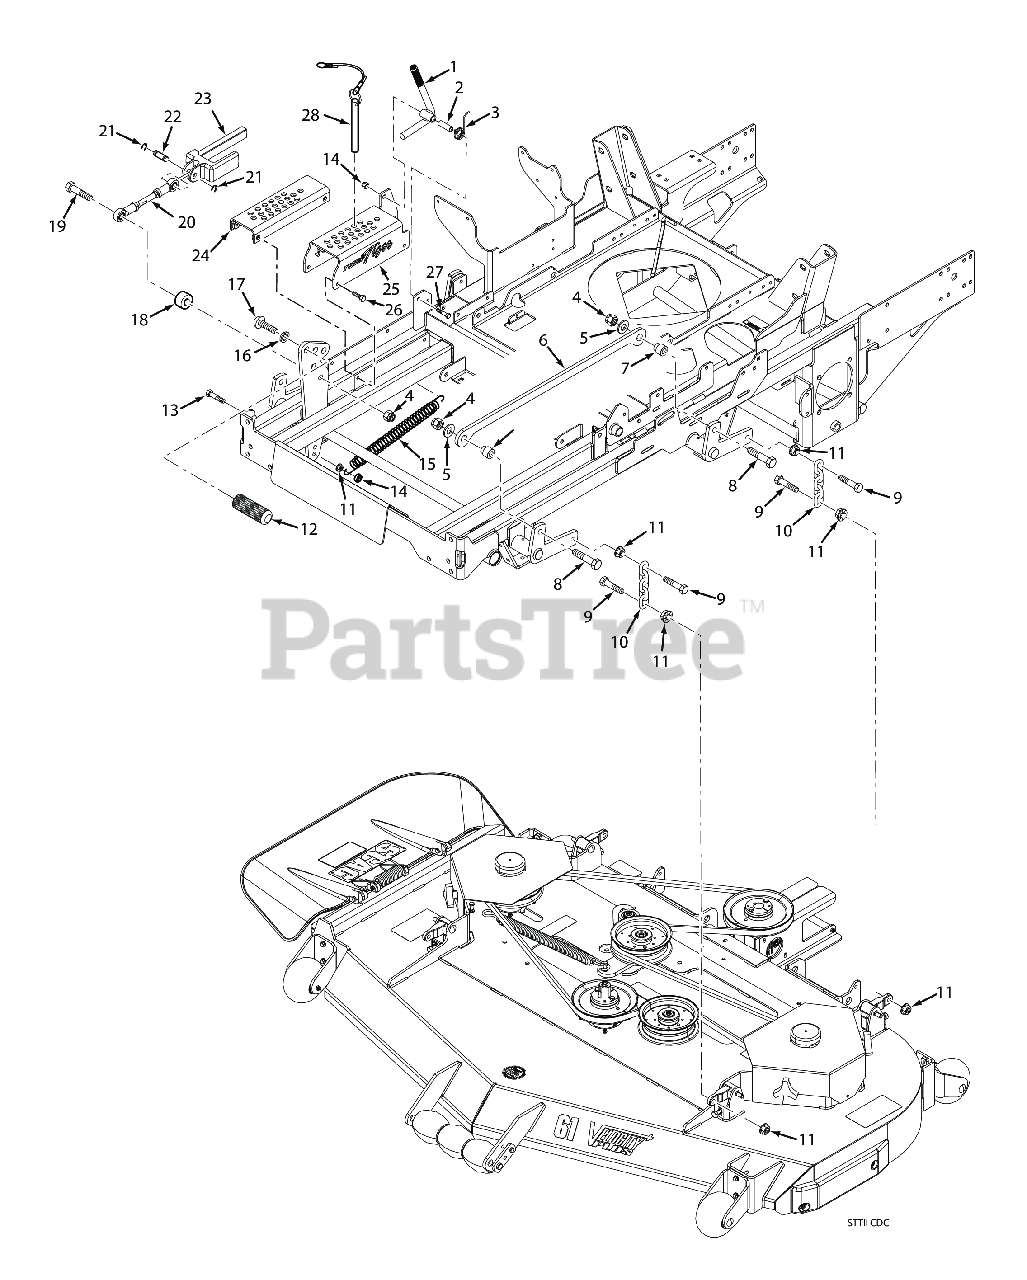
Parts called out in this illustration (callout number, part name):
1	Deck Latch Weldment w/Grip
1	Mounting Bracket, Fuel Tank
2	Bushing, .502 O.D.
3	Spring, Torsion - Lever Return
4	HEX LOCKNUT, ELASTIC STOP, 1/2-13
5	Flat Washer, 1/2 (.562 x 1.375 x .109)
6	Link, Deck Lift
7	Pivot, Deck Link
8	Bolt, Hex Head 1/2-13 x 2-1/4"
9	Bolt, Hex Head, 3/8-16 x 1-1/2"
10	Footplate
11	NUT, 3/8-16 SERRATED FLANGE HEX HEAD
12	Foot Pedal, Height Adjustment
13	Bolt, Hex Head 3/8-16 x 1-1/2" Grade 8 Black
14	Bolt, Hex Head 3/8-16 x 1" Ser. Flg.
15	Spring, Helper (61" & 72" Cutter Decks Only)
16	Lockwasher, 5/8" Spring
17	Bolt, Head Socket 5/8-11 x 1-1/2"
18	Spacer, Radiator
19	Hex Head Bolt, 1/2-13 x 2"
20	Linkage Assembly, Deck Lift
21	Retaining Ring, 1/2" Ext. "E"
22	Pin, Deck Lift
23	Slide, Height Adjustment
24	Weldment, Lower Cutting Height
25	Adjustment Bracket, Cutting Height Upper
26	Bolt, Hex Wshr Head 5/16-18 x 1-1/4"
27	Bolt, Hex Head 3/8-16 x 2-1/4" - 61"
28	Lanyard, Deck Height Pin Assembly
